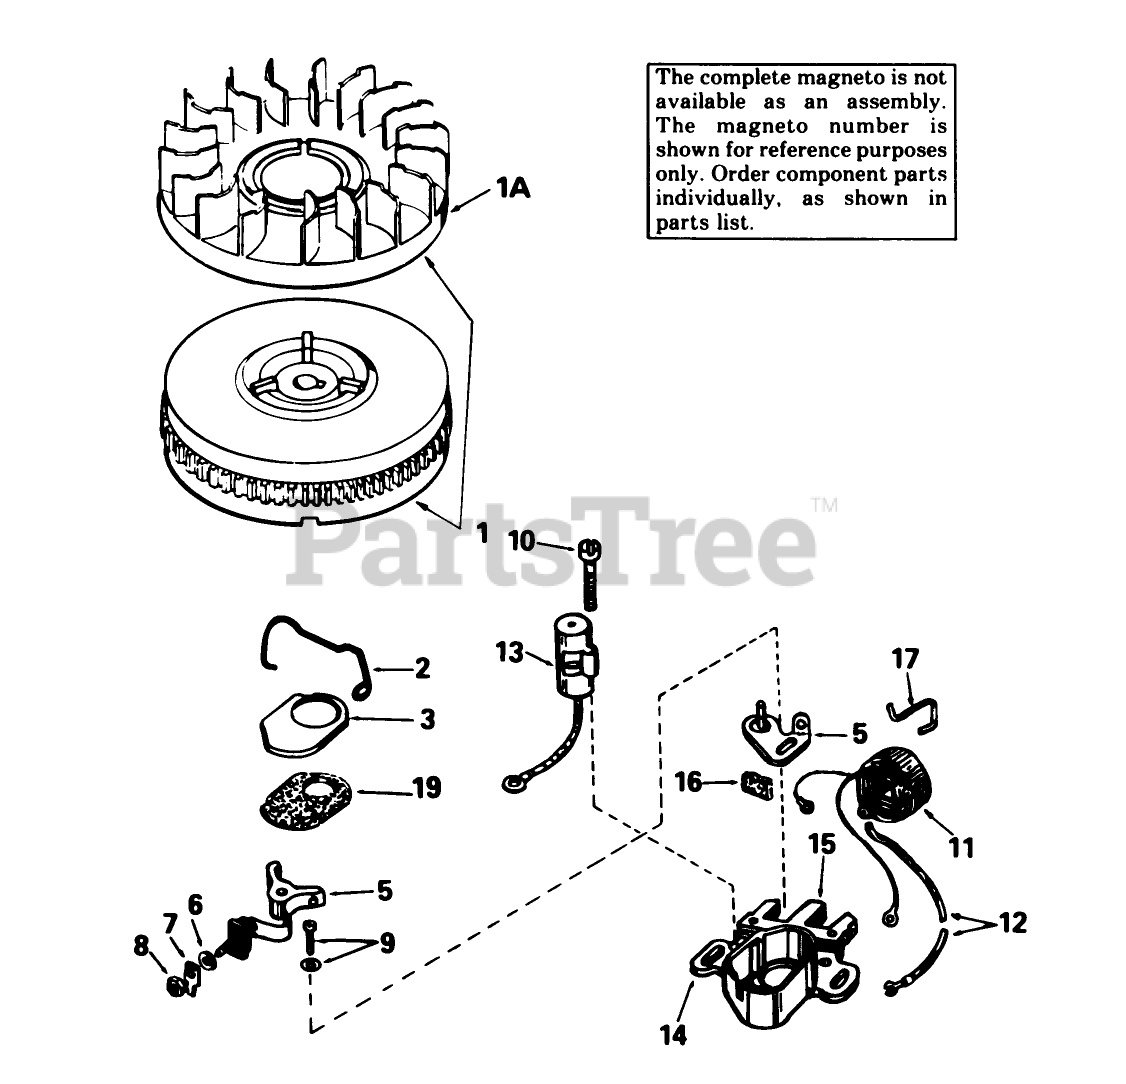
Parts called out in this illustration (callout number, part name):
1	Flywheel (Incl. Ref. #1A)
2	Spring Breaker Box
3	Cover-Dust
5	Breaker Assy.
6	Washer
7	Terminal, Ground
8	DECAL
9	Breaker Screw
10	Condenser Screw
11	Coil Assy. (Incl. No. 12)
12	Wire, Lead
13	Condenser
14	Core Plate
15	Stator Assy. (Incl. Ref. #2 thru 11, 13, 14, 16, 17 19)
16	Felt,Cam Wiper
17	Clip, Coil
19	Gasket, Dust Cover
